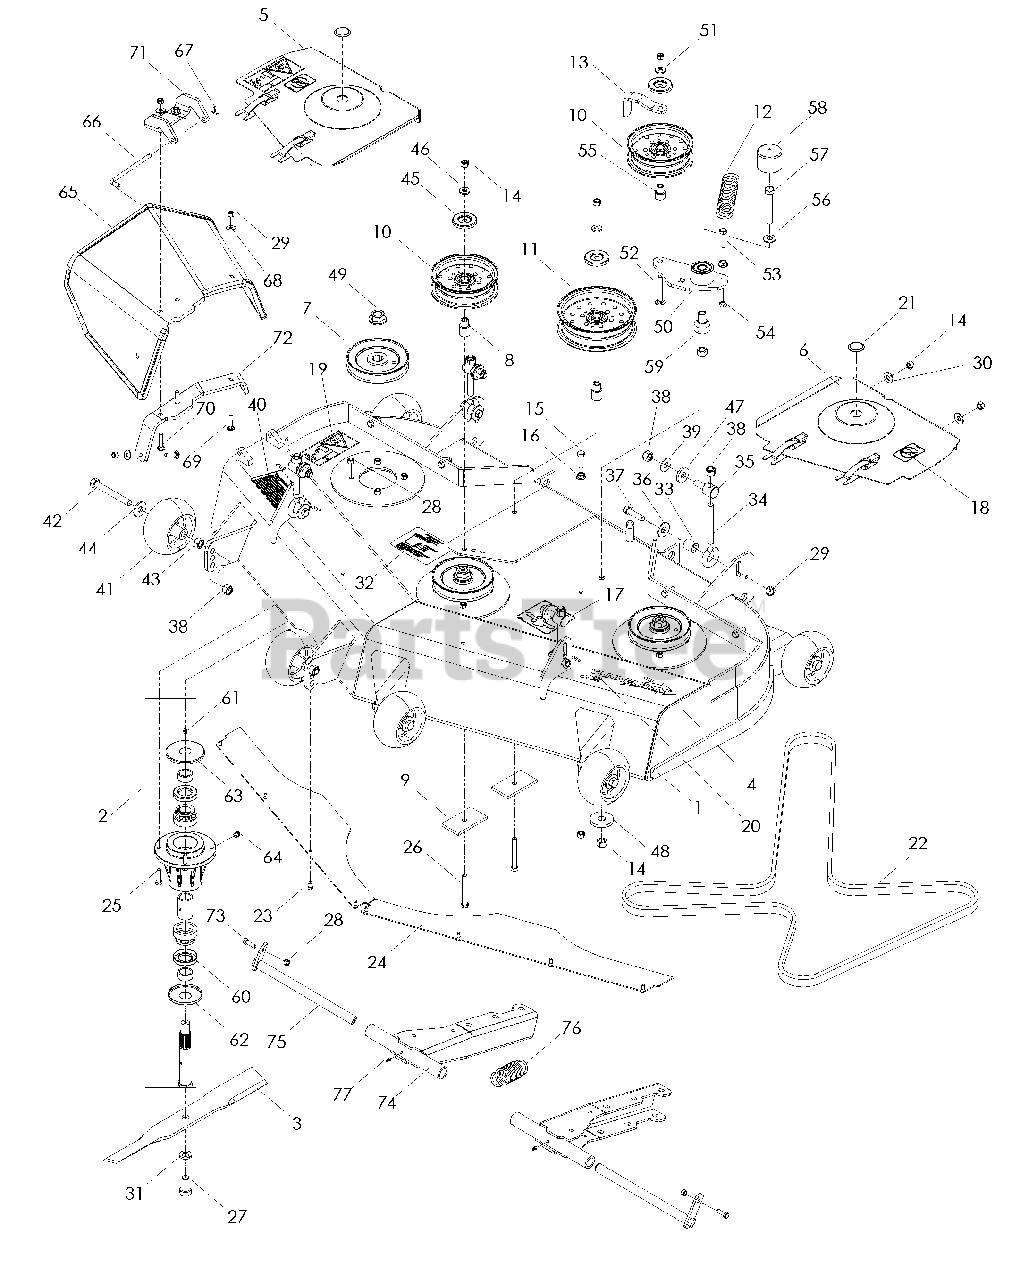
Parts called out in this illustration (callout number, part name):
1	Deck W/Decals
2	Housing Assm
3	Blade, 18"
4	Decal, Tunnelram
5	Belt Shield Rt
6	Belt Shield Lt
7	Pulley, 52
8	Bushing, Idler
9	Pad
10	Pulley, Idler
11	Pulley, Idler (Wide)
13	Guide, Belt
14	Nut 3/8-16 Hex Nyloc
15	Hcs 3/8-16 x 1 1/4
16	Nut 3/8-16 Whizlk
17	Decal, Belt Routing
18	Decal, No Step
19	Decal, Severing
20	Decal, 132
21	Button Plug 1"
22	Belt, 52" Deck
23	Screw 1/4-20 Slf Tap
24	Plate, Confinement
25	Hcs 5/16-18 x 1 1/4
26	Hcs 3/8-16 x 3
27	Hcs 5/8 x 1 1/4
28	Nut 5/16-18 Hex Nyloc
29	Nut 7/16-14 Ctrlk Gr A
30	Washer 3/8 Std Flat
31	Washer 5/8 Slw
32	Decal, Anti-Scalp
36	Washer 1/2 Spring
37	Hcs 7/16-14 x 1 3/4
38	Nut 1/2-13 Hex Nyloc
39	Washer 1/2
40	Decal, Discharge
41	Wheel, Gauge
42	Hcs 1/2-13 x 4
43	Nut 1/2-13
44	Washer 1/2
45	Shield, Dust
46	Washer 3/8 Thick
48	Washer, Support
49	Nut 3/4-16 Flanged
50	Arm, Idler W/Bearings
51	Washer 3/8 Thick
52	Rhsnb 3/8-16 x 2 3/4
53	Hcs 3/8-16 x 1 1/2 Gr8
54	Nut 3/8-16 Jam
55	Bushing, Idler
56	Washer 1/2 Belleville
57	Hcs 1/2-13 x 3 1/4
58	Cap, Vinyl
59	Pivot, Bearing
60	Seal, Shaft
62	Dust Cap, Bottom
63	Dust Cap, Top
64	Poppet, Grease
65	Discharge Chute
66	Pin, Chute Pivot
67	Pin, Cotter 1/8 x 3/4
68	Washer 5/16
69	Rhsnb 5/16-18 x 1 1/4
70	Rhsnb 5/16-18 x 1 1/2
71	Bracket, Chute
72	Reinforcement, Brcket
73	Hcs 5/16-18 x 1
75	Pin, Pivot
76	Spring, Extension
77	Zerk
